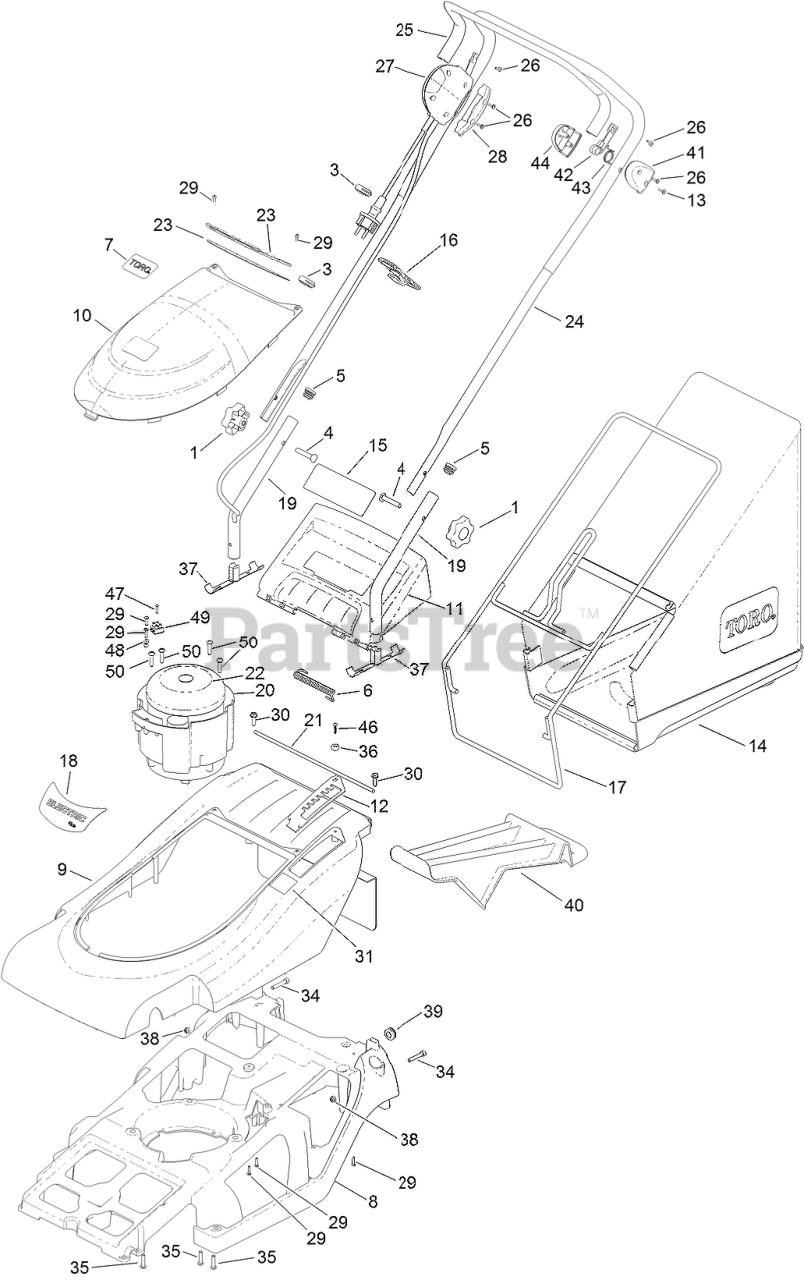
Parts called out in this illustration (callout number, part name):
1	KNOB-HANDLEBAR
3	CLIP-CABLE
4	BOLT-HANDLEBAR
5	PLUG-TUBE
6	SPRING-DEFLECTOR
7	DECAL-TORO
9	TOP-COVER
10	COVER-MOTOR
11	MOULDING-DEFLECTOR, REAR
12	PLATE-HOC
13	SCREW-PPH
14	GRASSBAG
15	DECAL-SAFETY, ELECTRIC
16	CLEAT-CABLE
17	FRAME-GRASSBAG
19	HANDLEBARS-LOWER
20	MOULDING-MOUNT, ELECTRIC MOTOR
21	BAR-HINGE
22	MOTOR-INDUCTION, 1.5KW
23	MOULDING-VENT, SUPPORT
24	HANDLEBARS-ELECTRIC
25	ARM-BAIL
27	SWITCH AND LEAD ASM
28	SWITCH-LEFT, LOWER
30	SCREW-TAPTITE
31	DECAL-HOC
34	SCREW-SOCKET
36	CUP-SCREW, ELECTRIC
37	PLUG-HANDLEBAR
38	NUT-NYLOC
39	GROMMET-RUBBER
40	PLUG-MULCHING
41	MOUNT-LEFT
42	LEVER-MOUNT
43	SPRING-BAILARM
44	MOUNT-RIGHT
46	SCREW-PLASTITE
47	SCREW-DRIVE, PLASTITE
48	CLAMP-CABLE
49	BLOCK-TERMINAL
